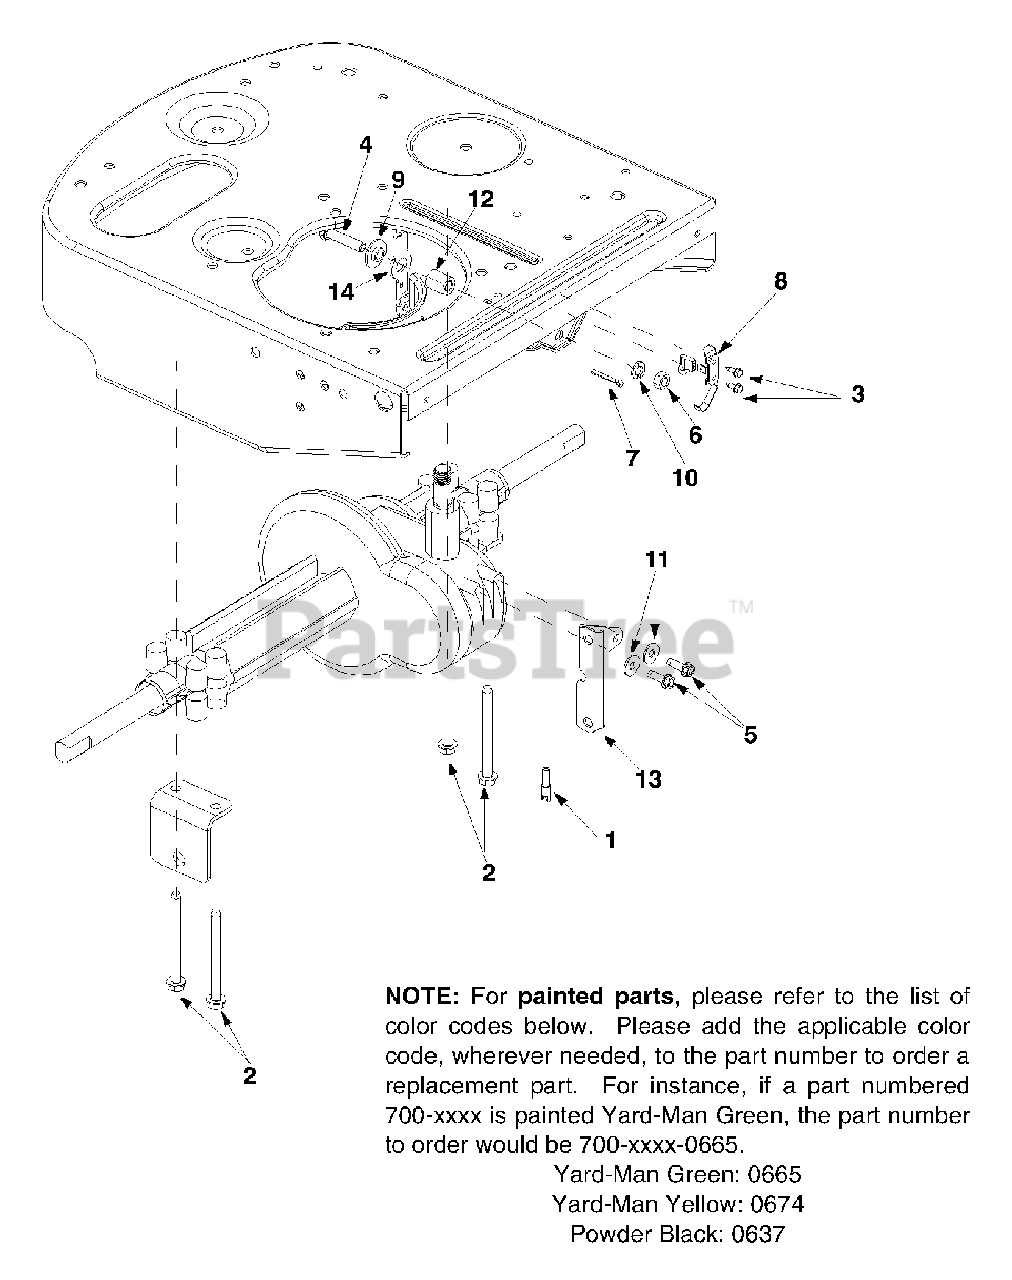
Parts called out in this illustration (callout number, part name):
1	Harness Assembly Adapter
2	Hex TT Screw 5/16-18 x 3.50
3	Hex Washer Head Self-Tap.Scew
4	Hex Screw 5/16-18 x 1.5 Gr. 5
5	Thd. Forming Scr. 1/4-20x .75
6	Hex Nut 5/16-18
7	Cotter Pin
8	Insulator Nut Plate
9	Shoulder Bushing
10	Lock Washer 5/16
11	Flat Washer
12	Spacer
